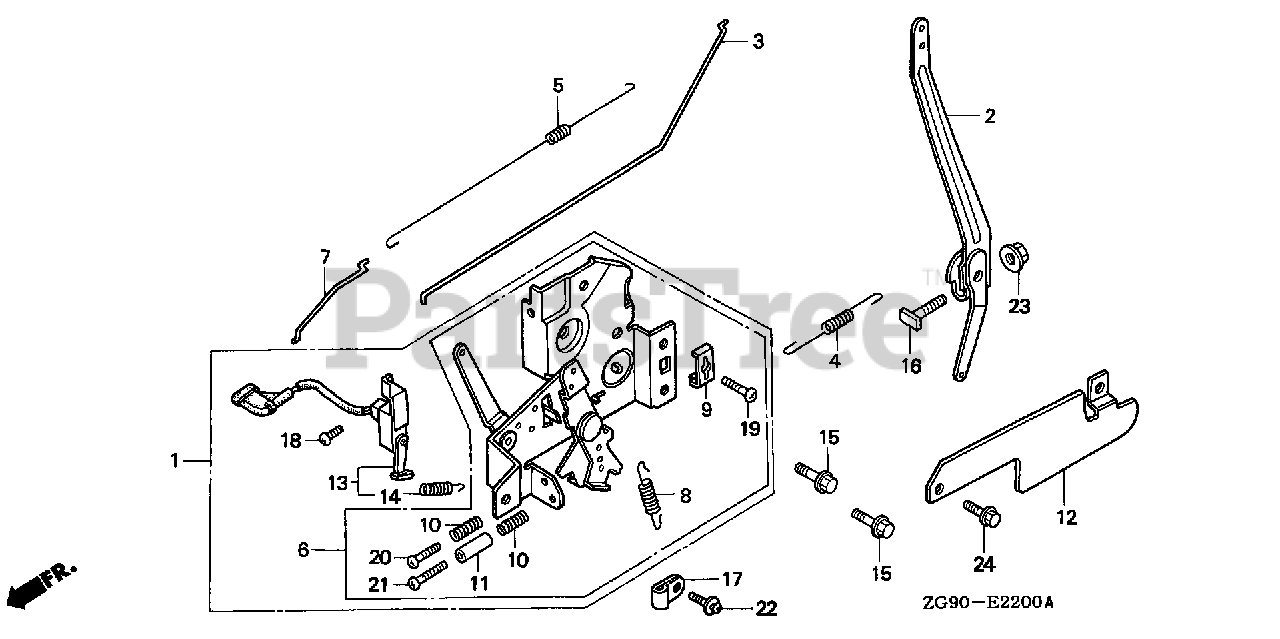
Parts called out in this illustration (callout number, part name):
2	ARM, GOVERNOR (C,G)
3	ROD, GOVERNOR
4	SPRING, GOVERNOR
5	SPRING, THROTTLE RETURN
7	ROD, CHOKE
8	SPRING, LEVER
9	HOLDER, CABLE
10	SPRING, CONTROL ADJUSTING
15	BOLT, FLANGE (6X14) (CT200)
16	BOLT, GOVERNOR ARM
17	CLIP (2.9MM)
19	SCREW, PAN (5X16)
20	SCREW, PAN (5X20)
21	SCREW, RECESSED (5X25)
22	SCREW-WASHER (4X12)
23	NUT, FLANGE (6MM)
